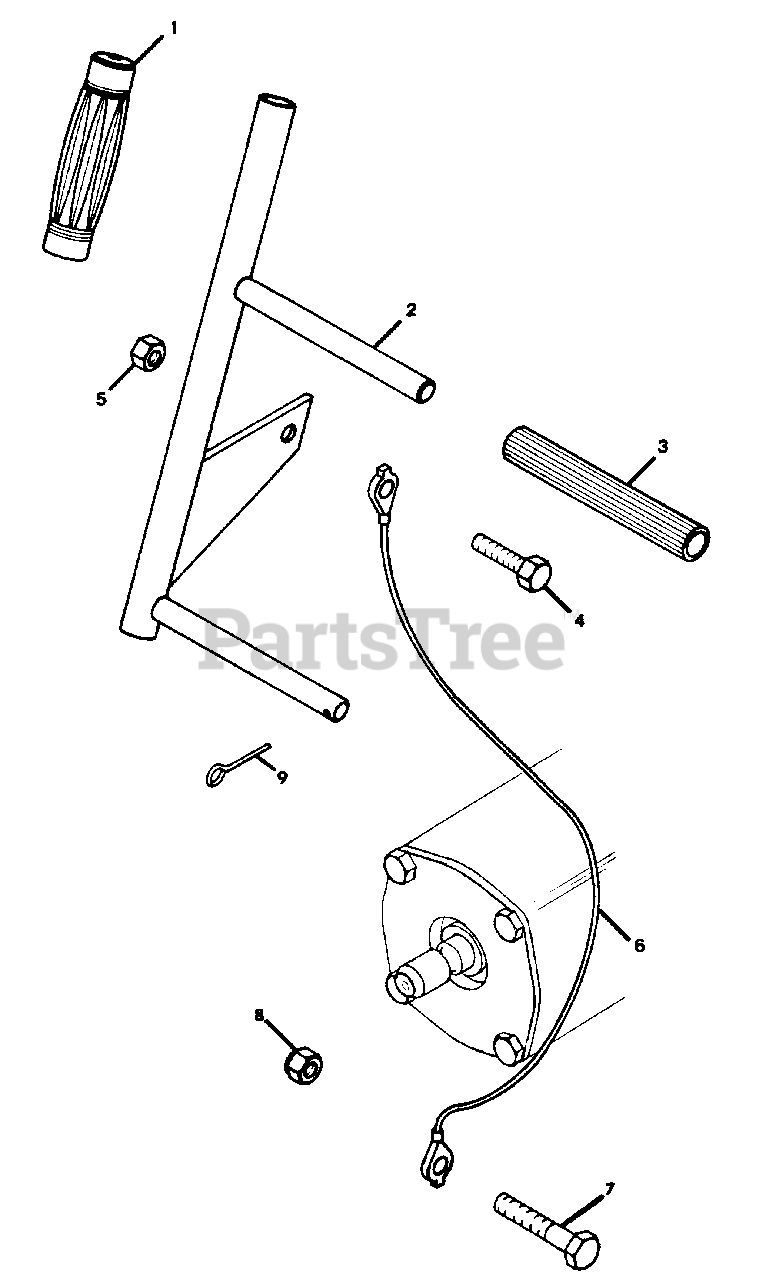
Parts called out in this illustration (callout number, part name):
1	GRIP, HAND
2	LEVER, LIFT
3	GRIP
4	BOLT, HEX 5/16-18X1.00
5	NUT, LOCK 5/16-18
6	CABLE, LIFT
7	BOLT, HEX 5/16-24X2.75
8	NUT, LOCK 5/16-24
9	PIN, COTTER .125X1.25
